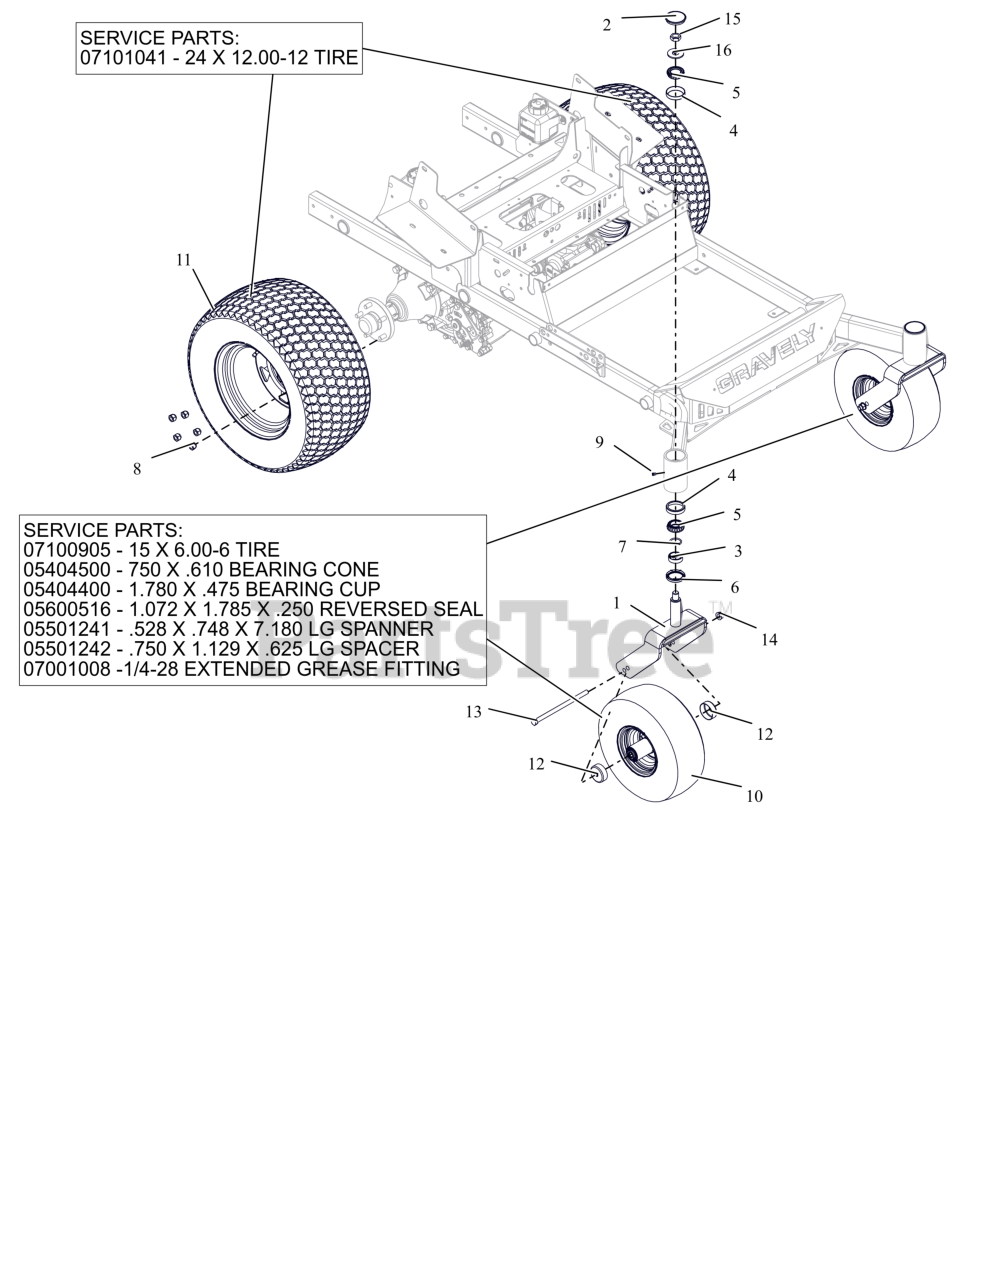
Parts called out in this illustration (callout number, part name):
1	CASTER FORK WMT - RED
2	CAP, DUST
3	SPCR, FRONT CASTER FORK
4	BRG-CUP 2.328X.465
5	BRG-CONE 1.25X.66
6	SEAL, OIL 1.75 X 2.332 X .312
8	NUT, WHEEL .50-20 ZCC
9	FTG, .25-28 FLUSH MNT GREASE
10	ASM, WHL/TIRE 15X6.00-6 SMOOTH
10	TIRE, 15X6-6 SMOOTH
10	BRG-CONE .750X.61
10	BRG-CUP 1.781X.475
10	SEAL,1.072X1.785X.250 REVERSED
10	SPANNER, .528X.748X7.18 LG
10	SPACER, .750X1.129X.625 LG
10	GREASE FITTING 1/4-28 EXTENDED
11	ASM, WHL/TIRE 24X12.00-12 K500
11	TIRE, 24 X 12.00-12
12	SHIELD, WHEEL BEARING
13	BLT, HEX .50-13X9.00 G5 ZCC
14	NUT-LK-TOP-FLG .500-13 GF ZCC
15	NUT, JAM-TOPLOCK .750-16 ZCC
16	WSHR-FL-STL 0.812X2X0.148 ZCC
